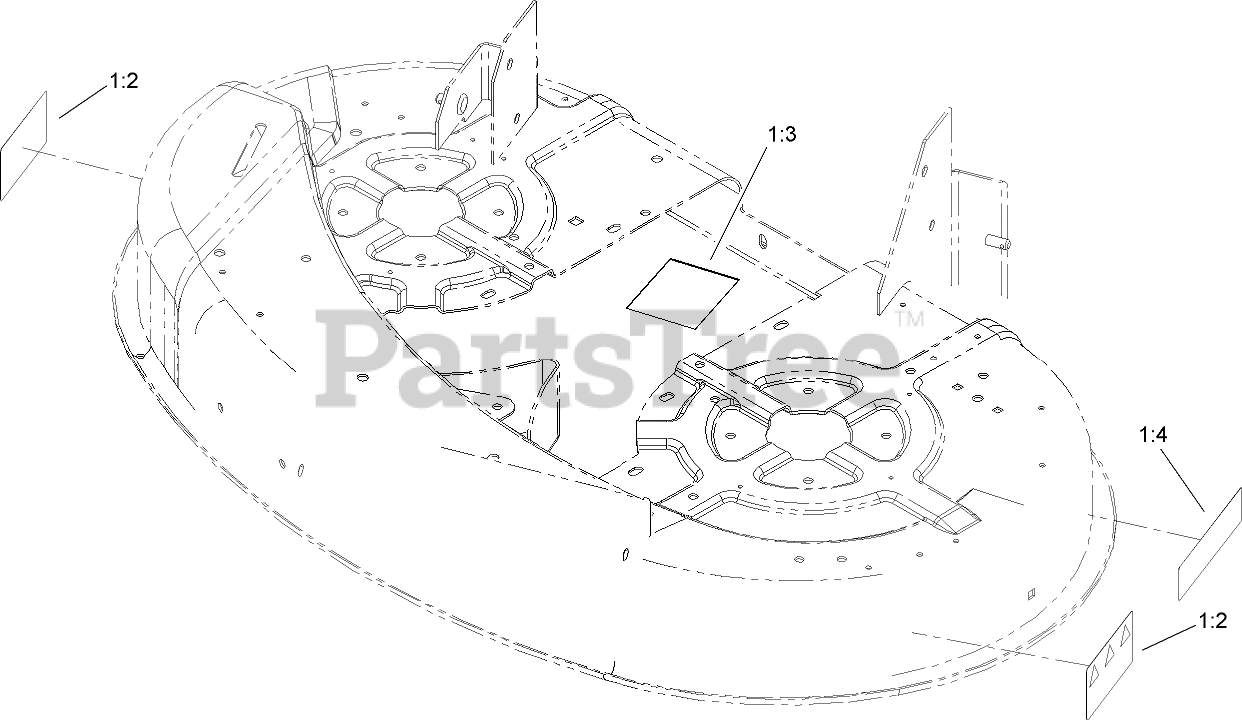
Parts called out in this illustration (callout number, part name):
1	DECK-38 INCH DC W/DECALS
1:2	DECAL-DANGER
1:3	DECAL-BELT ROUTING
